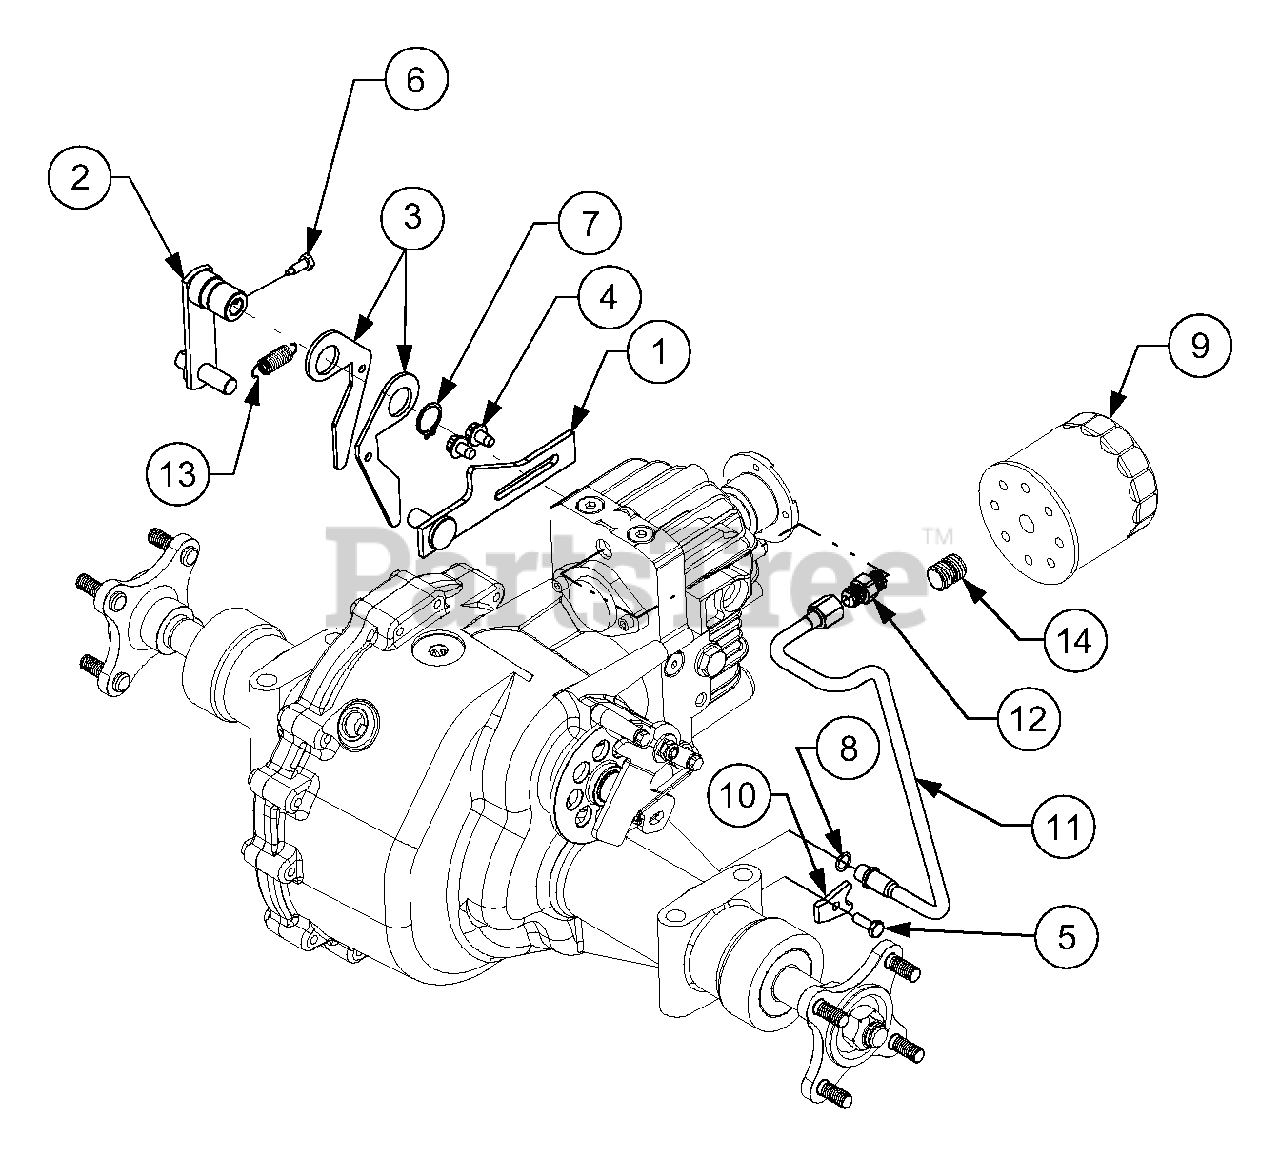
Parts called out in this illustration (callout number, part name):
1	Bracket, Neutral Return
2	Arm Assembly, Control
3	Arm, Neutral
4	Screw, Hex Wash Hd Tapp, 5/16-18 x .50
5	Screw, Hex Cap, 1/4-20 x .75 GR5
6	Screw, Special Hex Cap, 5/16-24 x .625
7	Ring, Snap, .875 Shaft
8	O-Ring, .426 ID x .566 OD x .07
9	Filter, Oil
10	Clamp, Tube, .50
11	Tube, Hydro Pickup
12	Fitting, Hydraulic
13	Spring, Extension
14	Nipple, Oil Filter
